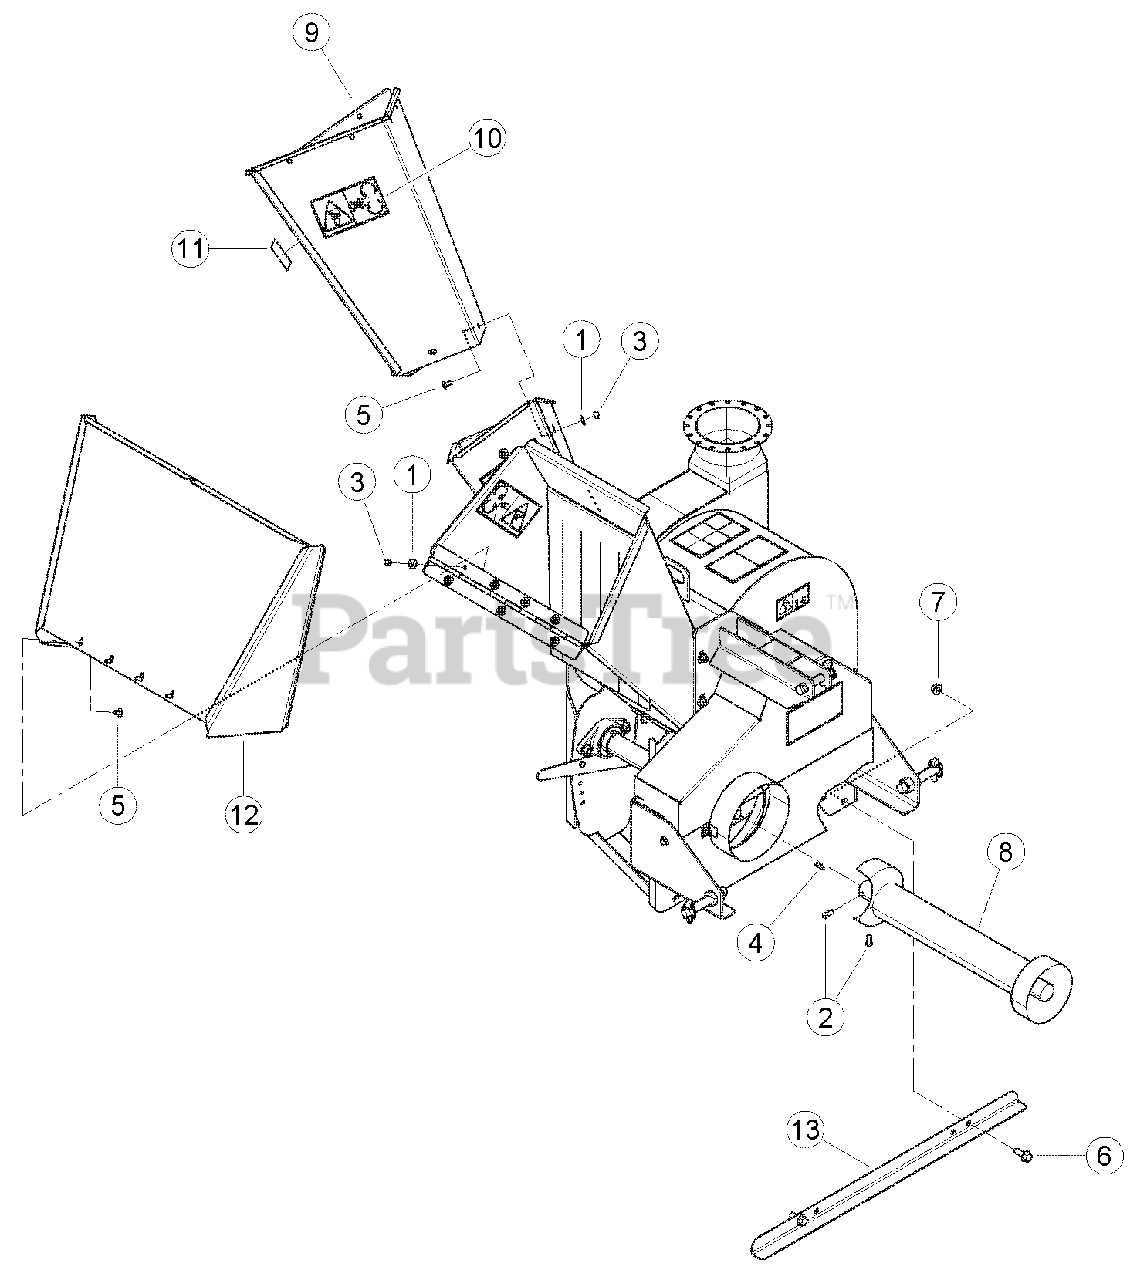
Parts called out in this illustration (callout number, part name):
1	WASHER, 5/16 FLAT ZP
2	SCREW, 3/8 X 3/4 SQ HD SET ZP
3	NUT, 5/16 NE NYLOCK ZP
4	KEY, 1/4 SQUARE X 1 LONG
5	BOLT, 5/16 X 3/4 CRG GR5 NC ZP
6	BOLT, 1/2 X 1-1/4 SERR FLANGE
7	NUT, 1/2 SERR FLANGE NC ZP
8	DRIVESHAFT, 540 C/S WS
9	ASSY, COMM. CHUTE EXTENSION SERVICE PART
10	DECAL, BLADE DANGER ISO
11	DECAL, MUTILINGUAL MANUAL
12	WELDMENT, CHUTE TRAY
13	LEG, C/S SUPPORT
